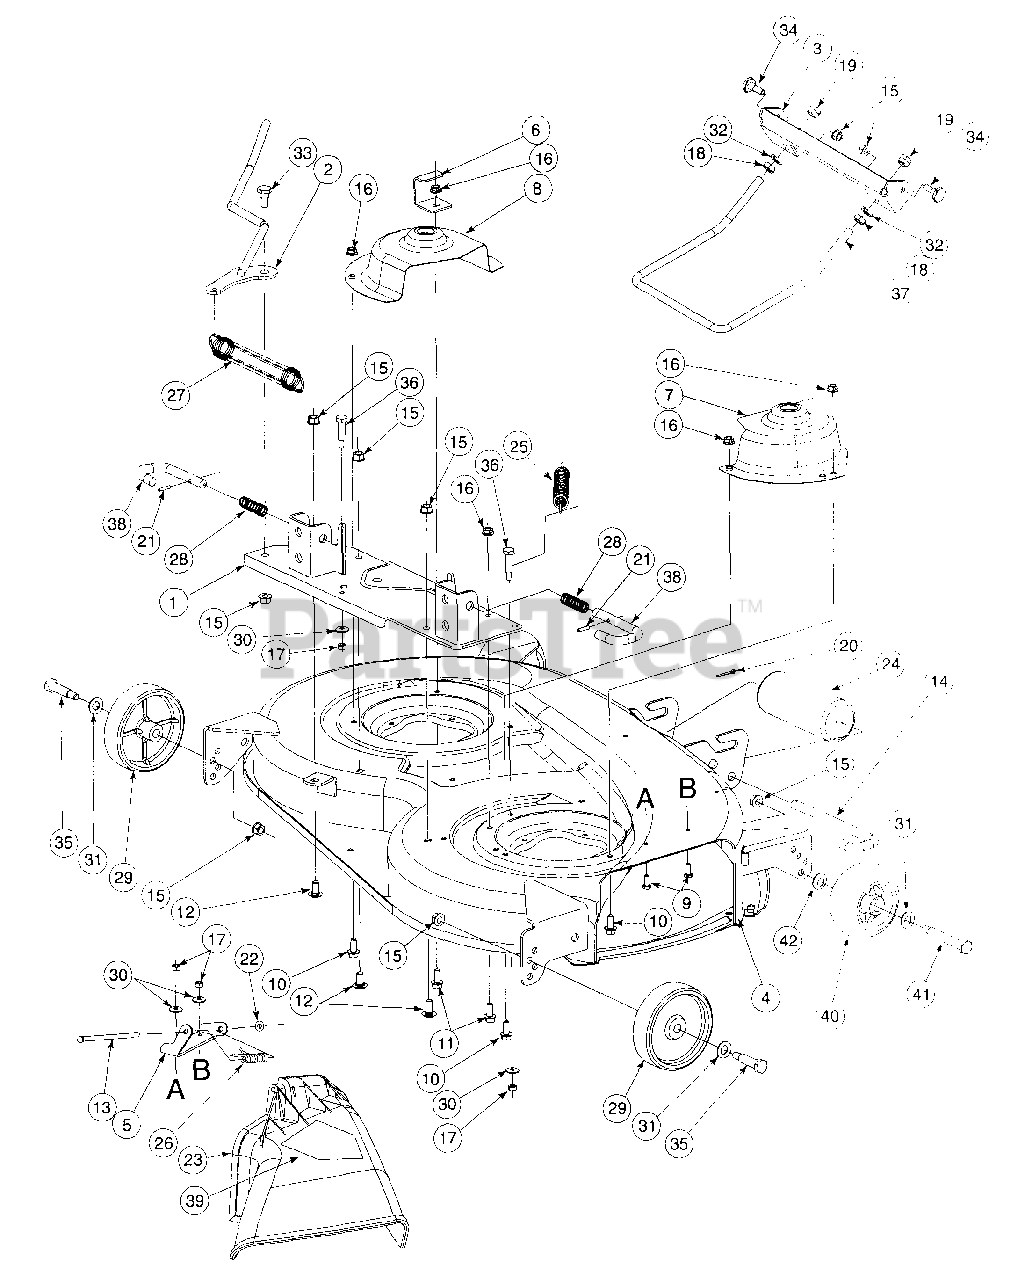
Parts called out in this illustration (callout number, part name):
1	Plate Assembly, Mounting
3	Bracket, Front Lift
4	Deck Assy, 42" w/out Front Wheels
4	Deck Assy, 42" w/Front Wheel brackets
5	Bracket, Hinge Mounting
6	Bracket, Handle Stop
7	Shield, RH Pulley
8	Shield, LH Pulley
9	Screw, Hex Cap, 1/4-20 x .62 GR5
10	Screw, Hx Wsh Hd Tapp, 5/16-18 x .75
11	Screw, Hex Cap, 5/16-18 x .75 GR5
12	Bolt, Carriage, 3/8-16 x .75
13	Pin, Hinge, .25 Dia x 6.75 Lg
14	Pin, Roller, 1/2 Dia x 7.31 Lg
15	Nut, Hex Flange Lock, 3/8-16
16	Nut, Hex Flange Lock, 5/16-18 GR5
17	Nut, Hex, 1/4-20
18	Nut, Hex Jam, 1/2-13 GR5
19	Nut, Hex Insert Lock, 1/2-13
20	Pin, Cotter, 3/32 x 1.25
21	Pin, Spirol Spring, 3/16 x .75
22	Cap, Speed Nut
23	Deflector Assy (Incl 5, 13, 22, 26)
25	Spring, Extension, .88 OD x 6.12
26	Spring, Torsion
27	Spring, Extension, 1.25 OD x 8.15
28	Spring, Compression
29	Wheel, Deck, 5 in. Dia
30	Washer, Bell, .265 x .75 x .062
31	Washer, Flat, .510 x 1.0 x .060
32	Washer, Lock, 1/2
33	Bolt, Shoulder, .498 Dia x .340 Lg
34	Bolt, Shoulder, .50 Dia x .434 Lg
35	Bolt, Shoulder, .498 Dia x 1.64 Lg
36	Bolt, Shoulder, .375 Dia x 1.16 Lg
37	Rod, Front Lift
38	Pin, Mower Support
39	Graphic, Danger
40	Wheel, Deck w/Fitting
41	Bolt, Shoulder, 1/2 x 2.5
42	Washer, Bell, .401 x .870 x .063
